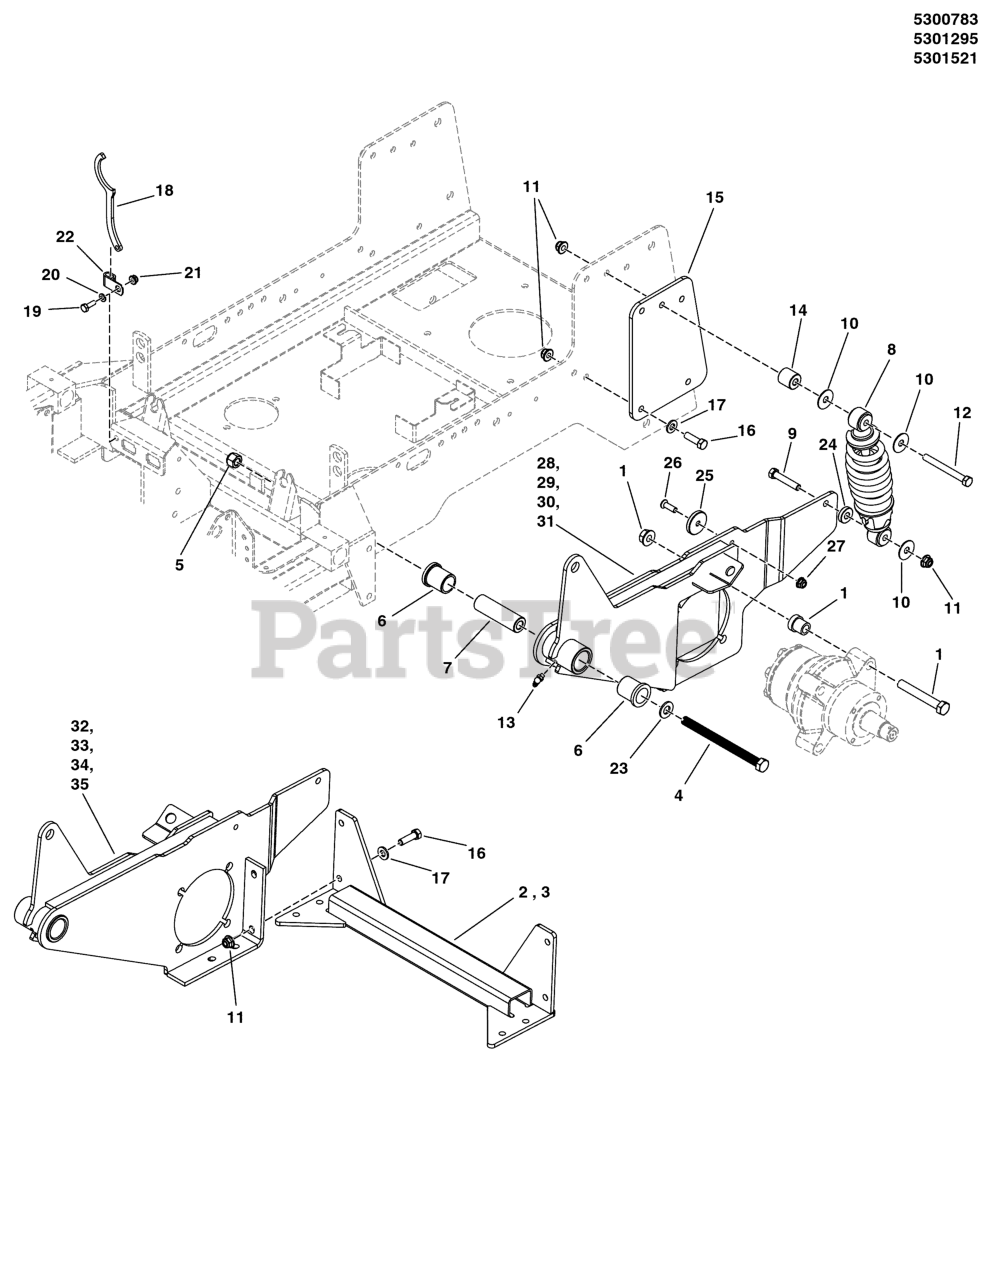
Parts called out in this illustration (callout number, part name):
2	KIT, TIE BAR
3	WELD, TIE BAR - BLK
4	BOLT, 1/2-13 X 6-1/2" GD8 YZ
5	NUT, 1/2-13 HEX NYLON LOCK
6	BUSHING, FLANGE
7	SPACER, .52 X 1.00 X 3.42
8	SHOCK ABSORBER
9	BOLT, 3/8-16 X 2, GD5, CZ
10	WASHER, 3/8" FENDER
11	NUT, 3/8-16 HEX NYLOCK FLANGE
12	BOLT, 3/8-16 X 3-1/2" GD5 CZ
13	GREASE FITTING, 45 DEGREE
14	SPACER, .390 X 1.00 X 1.00 - YZ
15	PLATE, FRAME SUPPORT - IS500 - RED
16	BOLT, 3/8-16 X 1-1/4" GD5 CZ
17	WASHER, 3/8" GD.9 FLAT
18	WRENCH, SPANNER, CZ
19	BOLT, 1/4-20 X 3/4" GD5 YZ
20	WASHER, 1/4 SAE
21	NUT, 1/4-20 HEX NYLOCK FLANGE
22	CLAMP, 5/16", DOUBLE, WIRE & TUBE
23	WASHER, 1/2 SAE
24	SPACER, .39 X 1.00 X .25
25	SPACER, .34 X 1.54 X .25 UHMW
26	SCREW, 5/16-18 X 1, PHILLIPS HD, BZ
27	NUT, 5/16-18 HEX NYLOCK FLANGE
28	WELD, MOTOR MOUNT, LH
29	WELD, MOTOR MOUNT, LH
30	WELD, MOTOR MOUNT, LH
31	WELD, MOTOR MOUNT, LH
32	WELD, MOTOR MOUNT, RH
33	WELD, MOTOR MOUNT, RH
34	WELD, MOTOR MOUNT, RH
35	WELD, MOTOR MOUNT, RH
